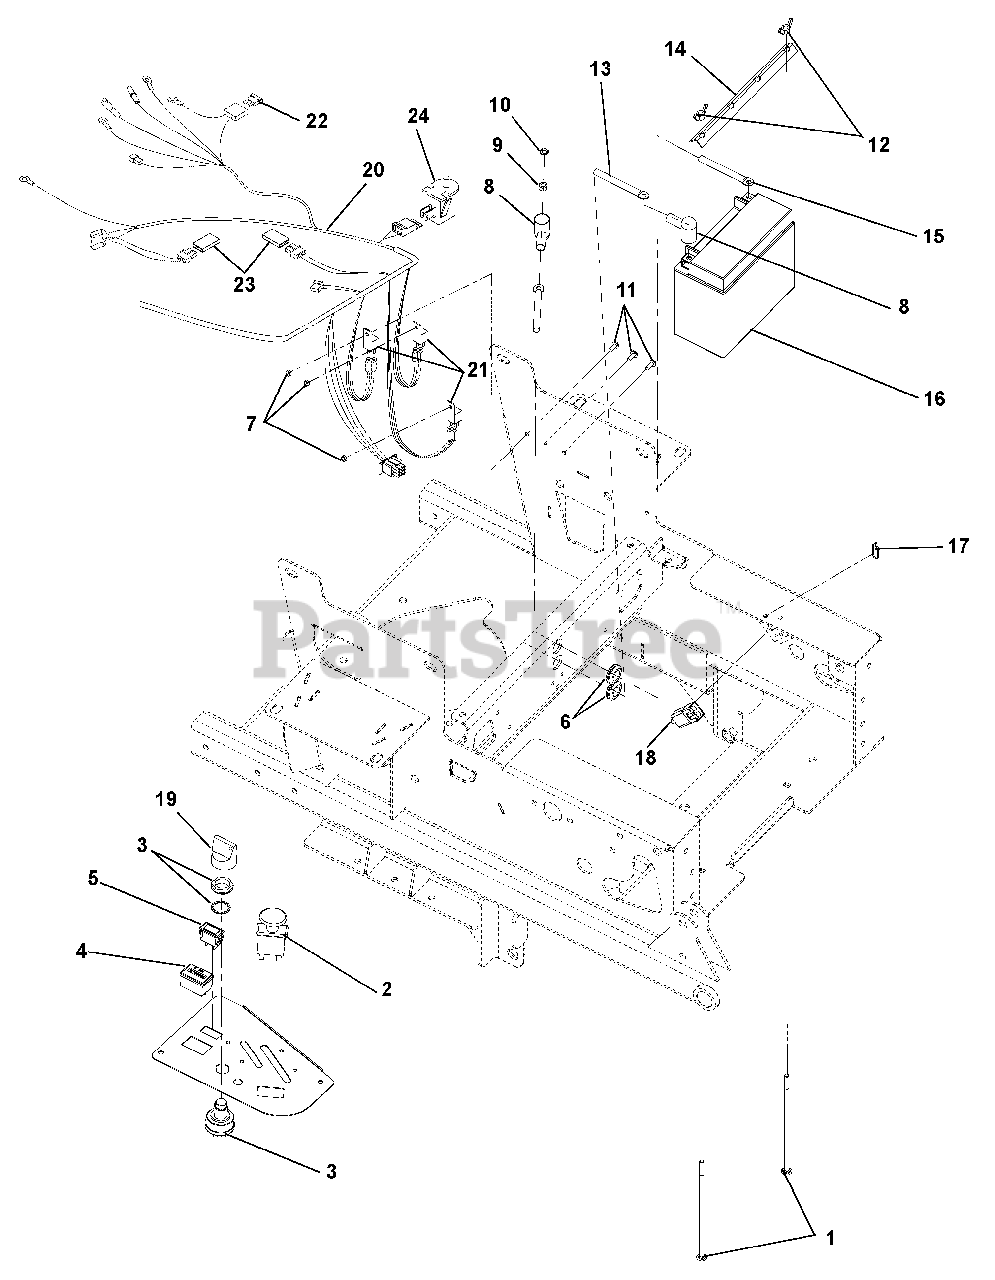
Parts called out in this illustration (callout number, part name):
1	BLT-RDHDSQNK .25-20X7.50 GR2YZ
2	SWITCH, CLUTCH
3	SWITCH, IGNITION
4	HOUR METER - DIGITAL
5	LIGHT,INDICATOR
6	GROMMET,RUBBER 5/8 ID/1.13 OD
7	NUT-LK-NYL 10-24 W/INSRT YWZC
8	BOOT, EYELET TERMINAL
9	NUT-HEX .25-20 YWZC
10	WSHR-LK-EXT.262X.502X.026YWZC
11	SCR-MCH 10-24X.50 HWH YWZC
12	NUT-LK WING .250-20 YWZC
13	CABLE-POSITIVE BATTERY 26.00"
14	HOLD DOWN
15	CBL,NEGATIVE BATTERY 20.00
16	BATTERY, 12 VOLT SEALED AGM
17	CABLE TIE LG 5-1/2
18	SWITCH, SNAP IN - N.O./N.O.
19	KEY, W/ SHIELD
20	HARNESS - IZ, CZ, 100I
21	RELAY,SEALED W/DIODE
22	FUSE, 30 AMP.
23	DIODE, CONNECTOR SHELL
24	SWITCH- SNAP MTG N.O.
